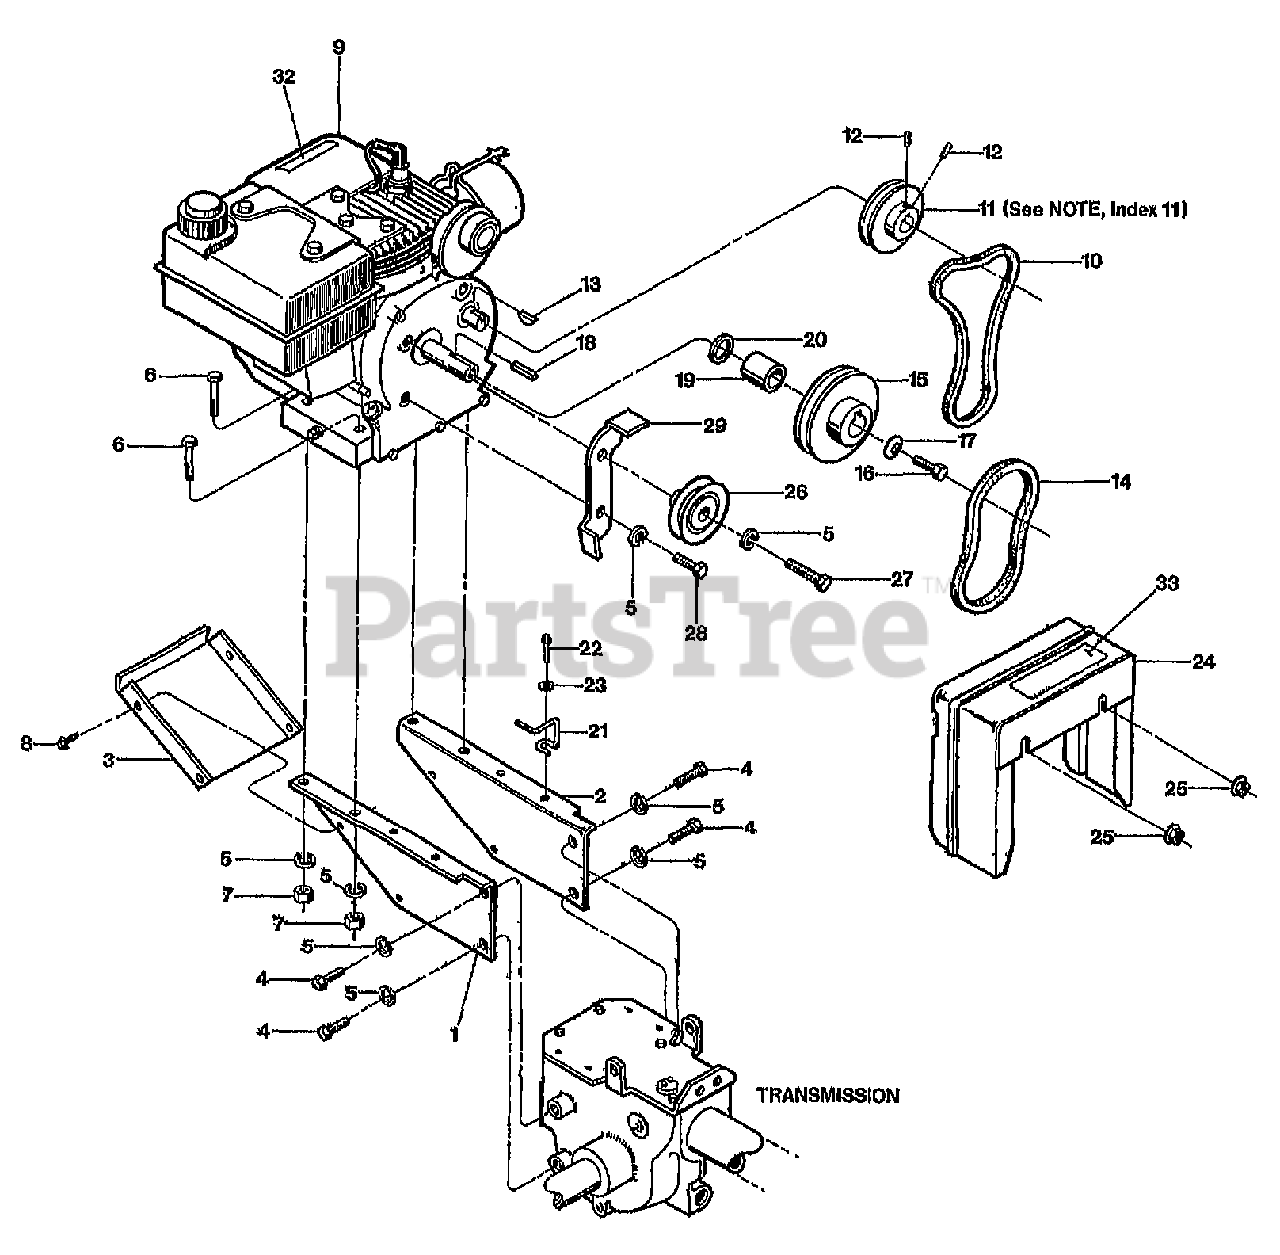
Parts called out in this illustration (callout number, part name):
1	BRKT-ENG LT P4
2	BRKT-ENG RT PNT
3	PAN-ENG BRKT PNT
4	SCR-HHC 5/16-18X.75 GR 5 ZP
5	WASHER-LK .312 ZP
6	SCR-HH 5/16-18X1.5 G5 ZP
7	NUT-HEX 5/16-18 ZP
8	SCR-HH SEMS 10-32 X .5 ZP (SEMS- W/PERM WSHR)
9	ENGINE
10	BELT-V (SEE V-BELT SET BELOW)
11	PULLEY-REVERSE (ENG DRIVEN, 1 GROOVE, 1 BELT)
12	SCR-SS 1/4-20 X .25 (SECUR REV ENG PULLEY)
13	KEY-WOODRUFF #5
14	BELT-V, FWD SMFRAME (SEE V-BELT SET BELOW)
15	PULLEY-FOWARD (ENG DRIVEN, 1 GROOVE, 1 BELT)
16	SCR-HH 3/8-24X1.0 G5 ZP (ATTACH FORW PULLEY)
17	WASHER-.994X.413X.145
18	KEY-.188 SQX1.0 (fwd plly to fwd pto shaft)
19	SPACER-.755X.937X1.375 (on fwd pto shaft)
20	SHIM-1.0X.7656X.031 (on fwd pto shaft)
21	GUIDE-BELT FWD
22	SCR-HWH 1/4-20 X .75 STH
23	WASHER-FLAT 1/4 SAE
24	CVR-BELT W/DEC P/JR OPC (incl #33)
25	NUT-HFLK 5/16-18 ZP
26	IDLER-V-GROOVE (internal bushing type)
27	BOLT-HH 5/16-24 X 1.5 ZP
28	SCR-HH 5/16-24X.50
29	GUIDE-BELT REV PNT (for rev idler pulley)
32	DECAL-STARTING STABIL
33	DECAL-BELT COVER OPC
